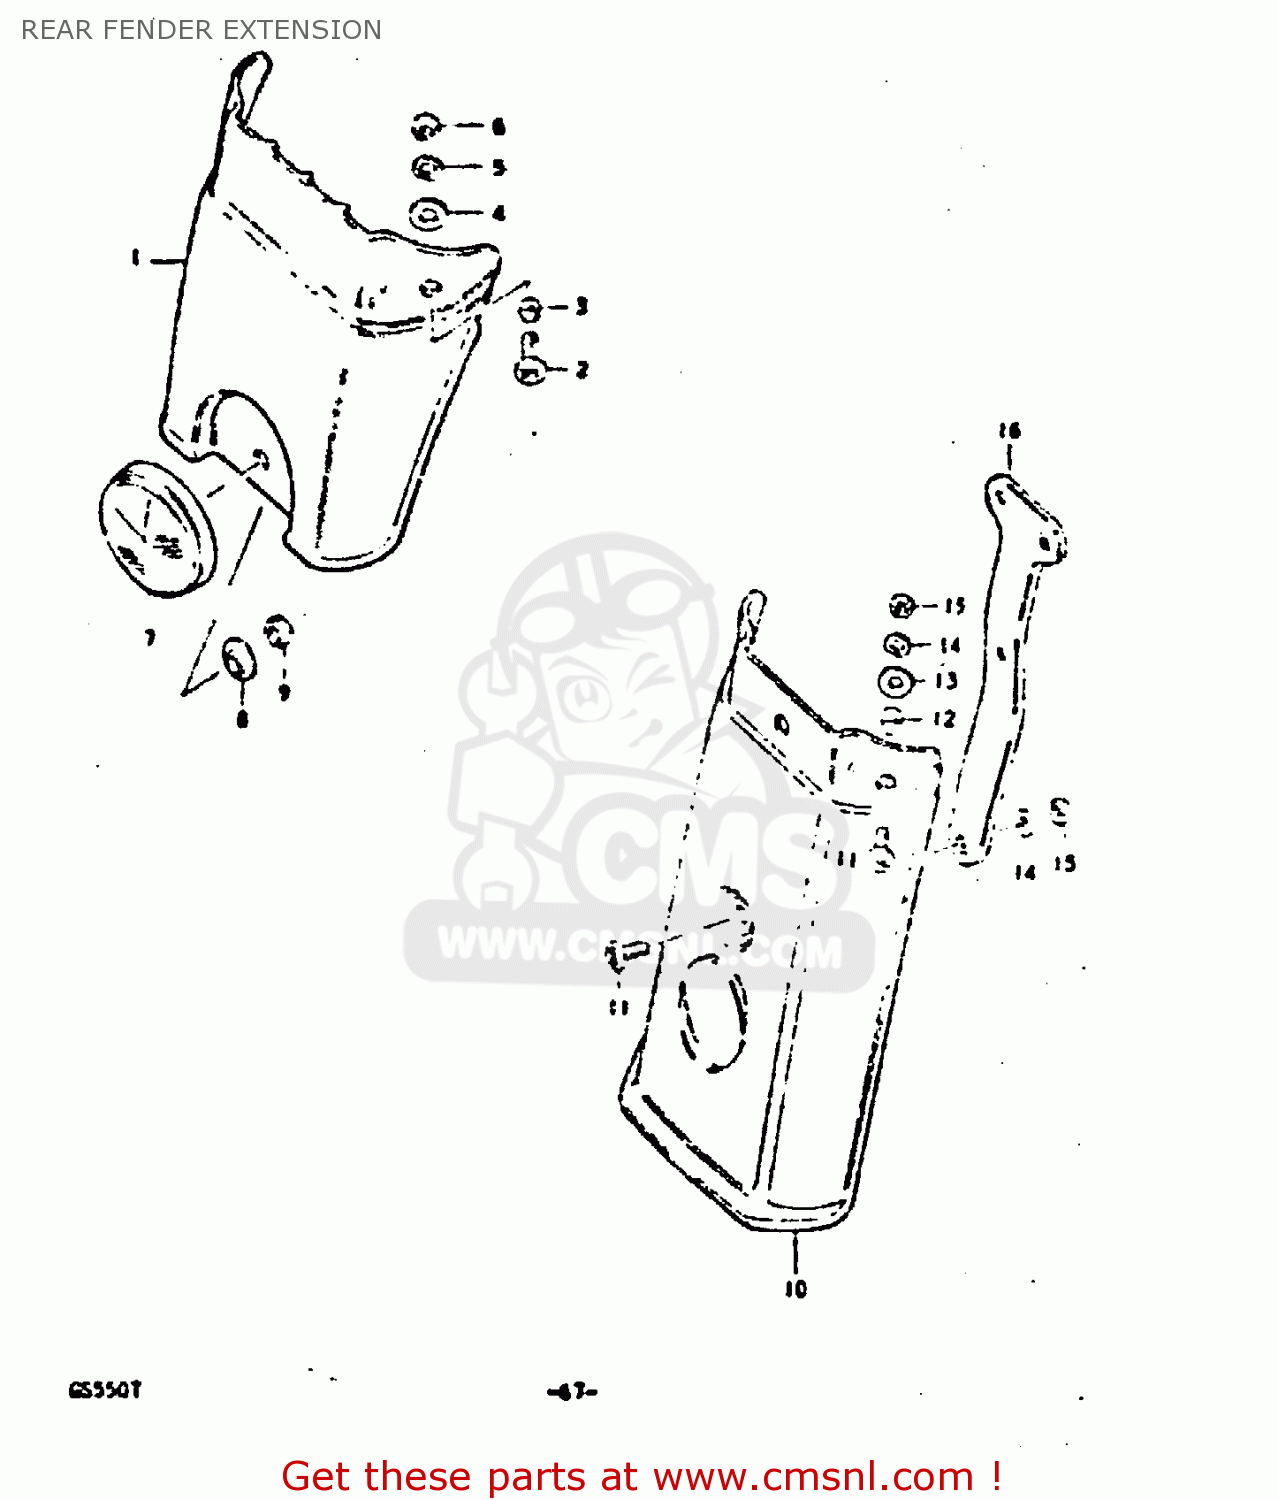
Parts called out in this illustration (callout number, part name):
1	EXTENSION, REAR FENDER
2	SCREW (6X15)
3	SPACER(6.2X8.3X5.7)
4	WASHER(6.5X18X1)
5	LOCK WASHER
6	NUT
7	REFLECTOR,REFLEX
8	SPACER
9	NUT
10	EXTENSION, REAR FENDER
11	SCREW (6X15)
12	SPACER(6.2X8.3X5.7)
13	WASHER(6.5X18X1)
14	LOCK WASHER
15	NUT
16	BRACE, REAR FENDER EXTENSION
